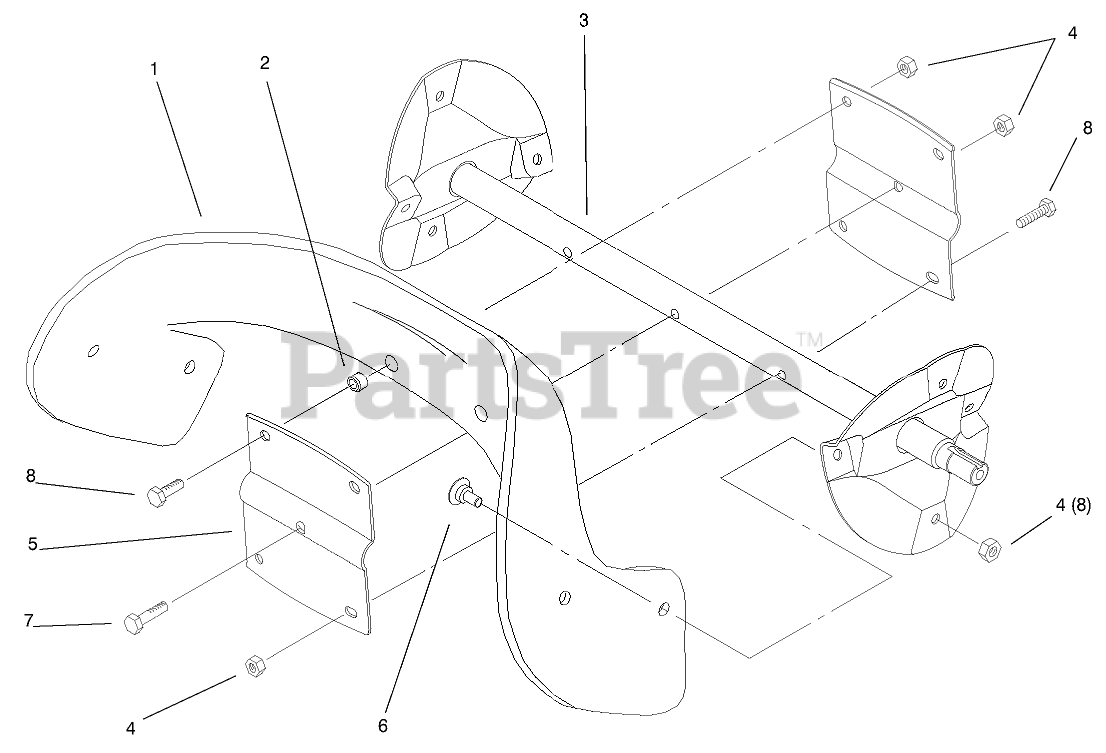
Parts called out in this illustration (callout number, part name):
1	BLADE-ROTOR
2	SPACER-BLADE, ROTOR
3	ROTOR ASM
4	NUT-LOCK, NI
5	HALF-ROTOR
6	SCREW
7	SCREW-HH
8	SCREW-HH
